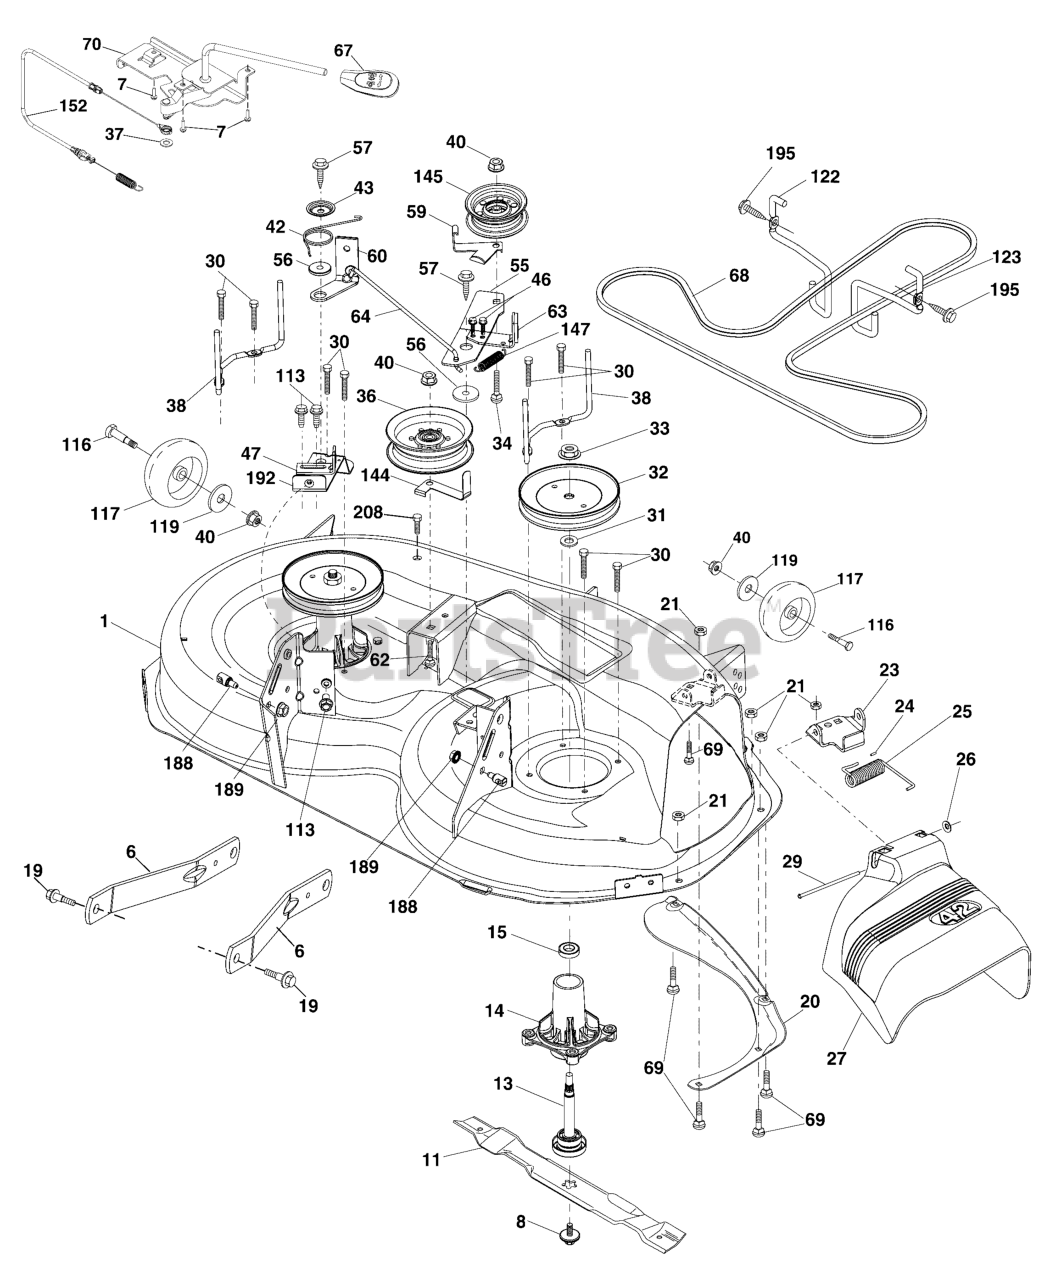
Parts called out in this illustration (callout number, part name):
1	HOUSING, Mower
2	BOLT, Round Head Square Neck, 5/16-18 UNC x 3/4
6	ARM, Suspension
7	SCREW, BOS Thread, 10 x .750
8	BOLT/WASHER, Assembly 7/16-20 UNF
11	BLADE, (For bagging or discharge)
13	SHAFT, Assembly Mandrel
14	HOUSING, Mandrel
15	BEARING, Ball, Mandrel
19	BOLT, Shoulder
20	BAFFLE, Vortex
21	NUT, Crownlock, 5/16-18 UNC
23	BRACKET, Deflector
24	CAP, Sleeve
25	SPRING, Torsion, Deflector
26	NUT, Push
27	SHIELD, Deflector
29	ROD, Hinge
30	SCREW, Thread Rolling Washer Head
31	WASHER, Spacer
32	PULLEY, Mandrel
33	NUT, Toplock, Flanged
34	BOLT, Carraige, 3/8-16 x 1-1/2, Gr 5
36	PULLEY, Idler
37	WASHER, 13/32 x 13/16 x 16 Ga.
38	KEEPER, Belt LH Mandrel
40	NUT, Lock Flange, 3/8-16 UNC
42	SPRING, Torsion Brake
43	SPRING, Torsion Retainer
46	SCREW, Thread Rolling, 1/4-20 x 5/8
47	BRACKET, Clutch Cable
55	ARM, Idler
56	SPACER, Retainer
57	SCREW, Hex Washer, 3/8-16 x 1
59	GUARD, Tuv Idler (94)
60	ARM, Brake Mower
62	BOLT, Round Head Square Neck, 3/8-16 UNC x 2
63	ARM, Brake Mower
64	LINKAGE, Brake
67	HANDLE, Clutch Cable
68	V-BELT
69	BOLT, Round Head Square Neck, 5/16-18 x 5/8
70	CLUTCH, Assembly Manual
113	SCREW, 5/16-18
116	BOLT, Shoulder
117	WHEEL, Gauge
119	WASHER, 13/32 x 7/8 x 14 Ga.
122	KEEPER, Belt Engine LH
123	KEEPER, Belt Engine RH
144	KEEPER, Belt
145	PULLEY, Idler Flat
147	SPRING, Return
152	CABLE, Clutch Manual w/Spr.
188	STUD, Fastener
189	NUT, Lock Hex Flange
192	BRACKET, Brake Stand LH
195	SCREW, Hex Washer, 3/8-16 x 3/4
208	SCREW, 3/8-16 x 1/2
